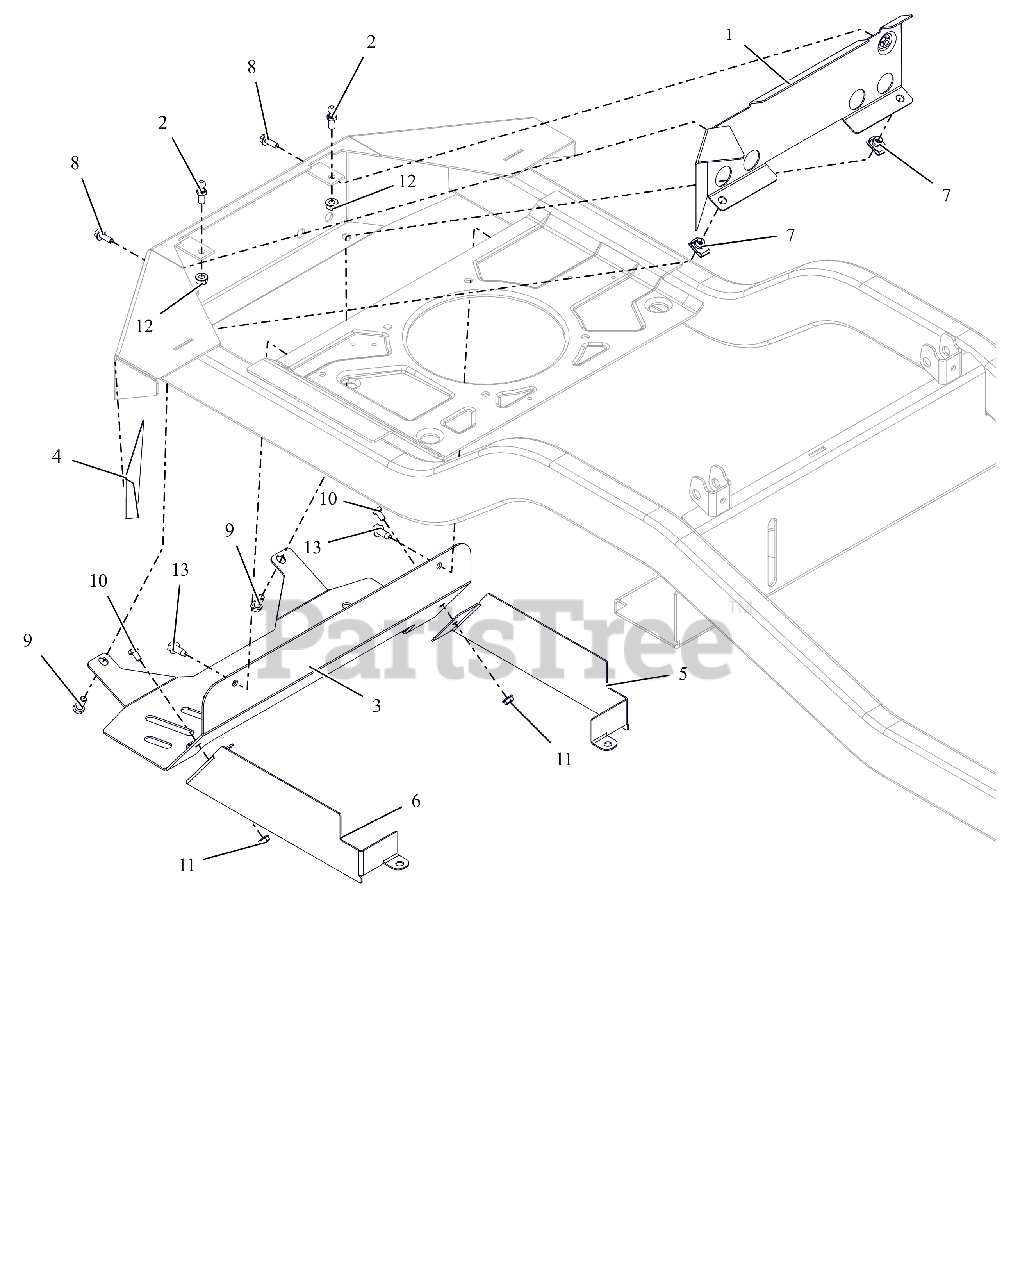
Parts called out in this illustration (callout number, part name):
1	WMT, HEAT BAFFLE
2	STUD- BALL
3	SHIELD, HEAT (HD)
4	TAPE, HEAT DEFLECTOR
5	GUARD,REAR CLUTCH LH
6	GUARD,REAR CLUTCH RH
7	NUT-CLIP RETAINER 5/16-18X.56
8	BLT,HEX-FLG .25-20X.75 G5 BFP
9	BLT,HEX .31-18X.75 G5 ZCC
10	BLT,HEX .25-20X.50 G5 ZCC
11	NUT-LK-TOP-FLG .250-20 GF ZCC
12	NUT,LK-CTR-FLG .31-18 GF ZCC
13	SCR,TAP .312-18X.75 HWH TR ZCC
